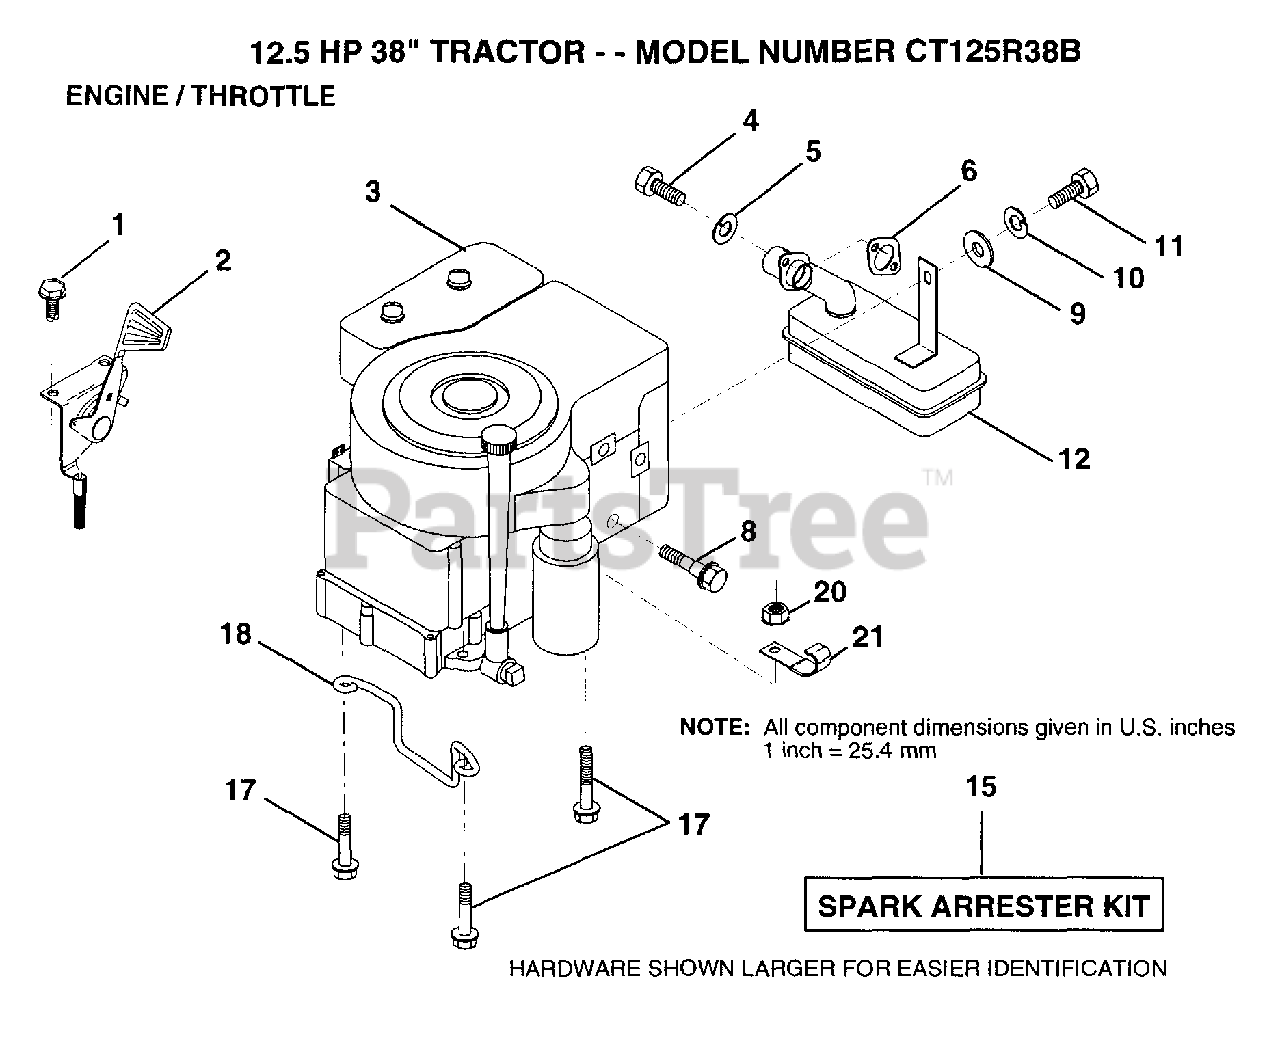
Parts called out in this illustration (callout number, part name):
1	SCREW.1/4-20X1/2
2	THROTTLE CONTROL
3	ENGINE, B&S
4	SCREW
5	LOCKWASHER
8	BOLT T
10	LOCKWASHER
12	MUFFLER
17	SCREW LT
18	"KEEPER,DR BELT GR"
20	NUT
21	CLIP T
